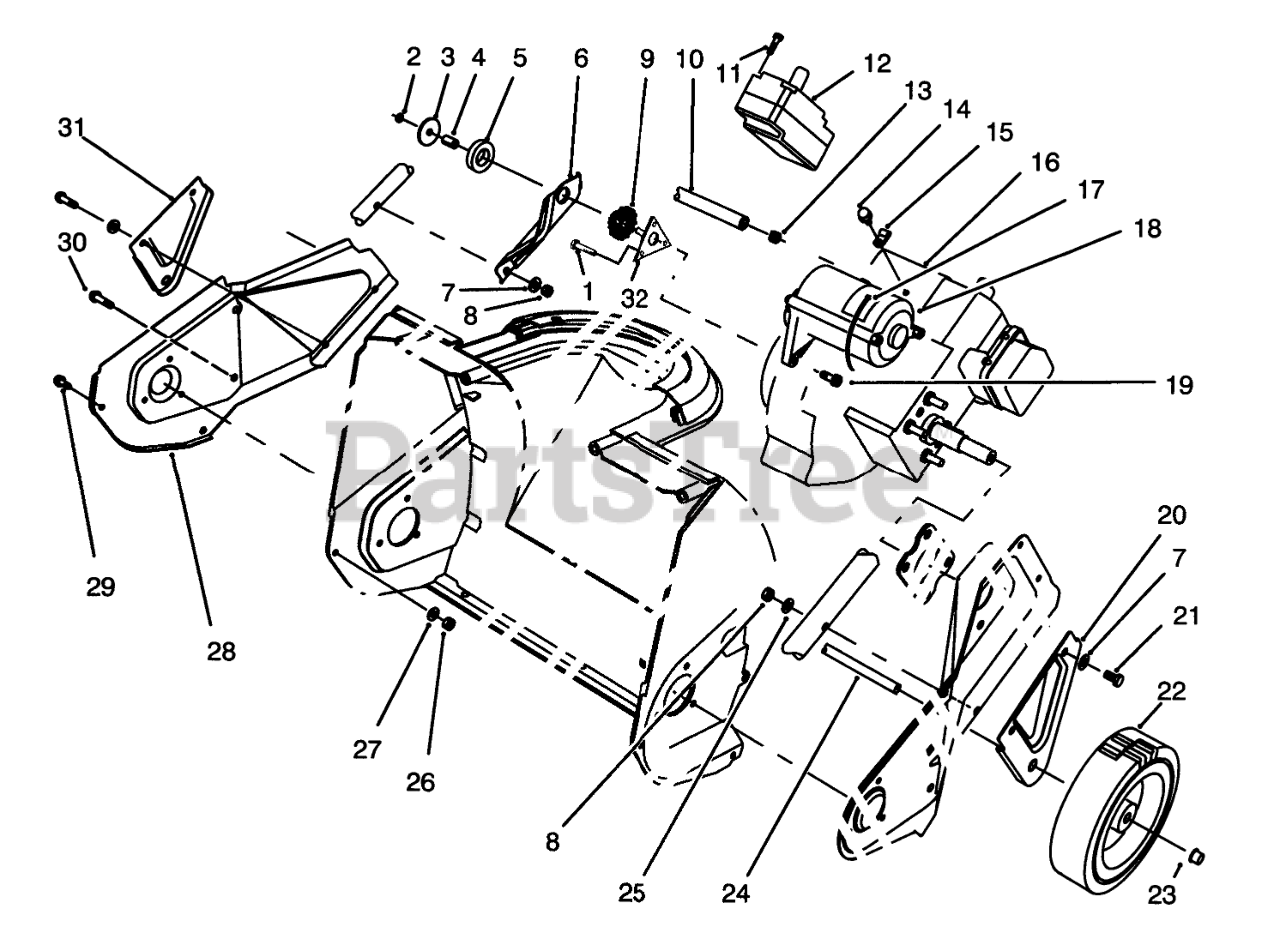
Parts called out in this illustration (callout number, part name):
1	SCREW X
2	NUT-LOCK, NI
3	WASHER-FLAT
4	SPACER-TUBULAR
5	Ring-Isolator
6	Support-Engine
7	WASHER-FLAT
8	NUT-LOCK, NI
9	BUSHING-ISOLATOR
10	LINE-GAS
11	SCREW-PLASTITE
12	ASM-Switch Housing
13	CLAMP-HOSE
14	SCREW-HWH
15	CLAMP
17	TIE-CABLE
18	ASM-Switch Housing
19	SCREW-HH, TORX
20	Bracket-Wheel
21	SCREW-HH
22	WHEEL
23	RETAINER-PUSH ON
25	WASHER
26	NUT-LOCK, NI
27	WASHER-FLAT
28	Sideplate-RH
30	SCREW-PLASTIC
31	Bracket-Wheel
32	BRACKET AND STUD ASM
